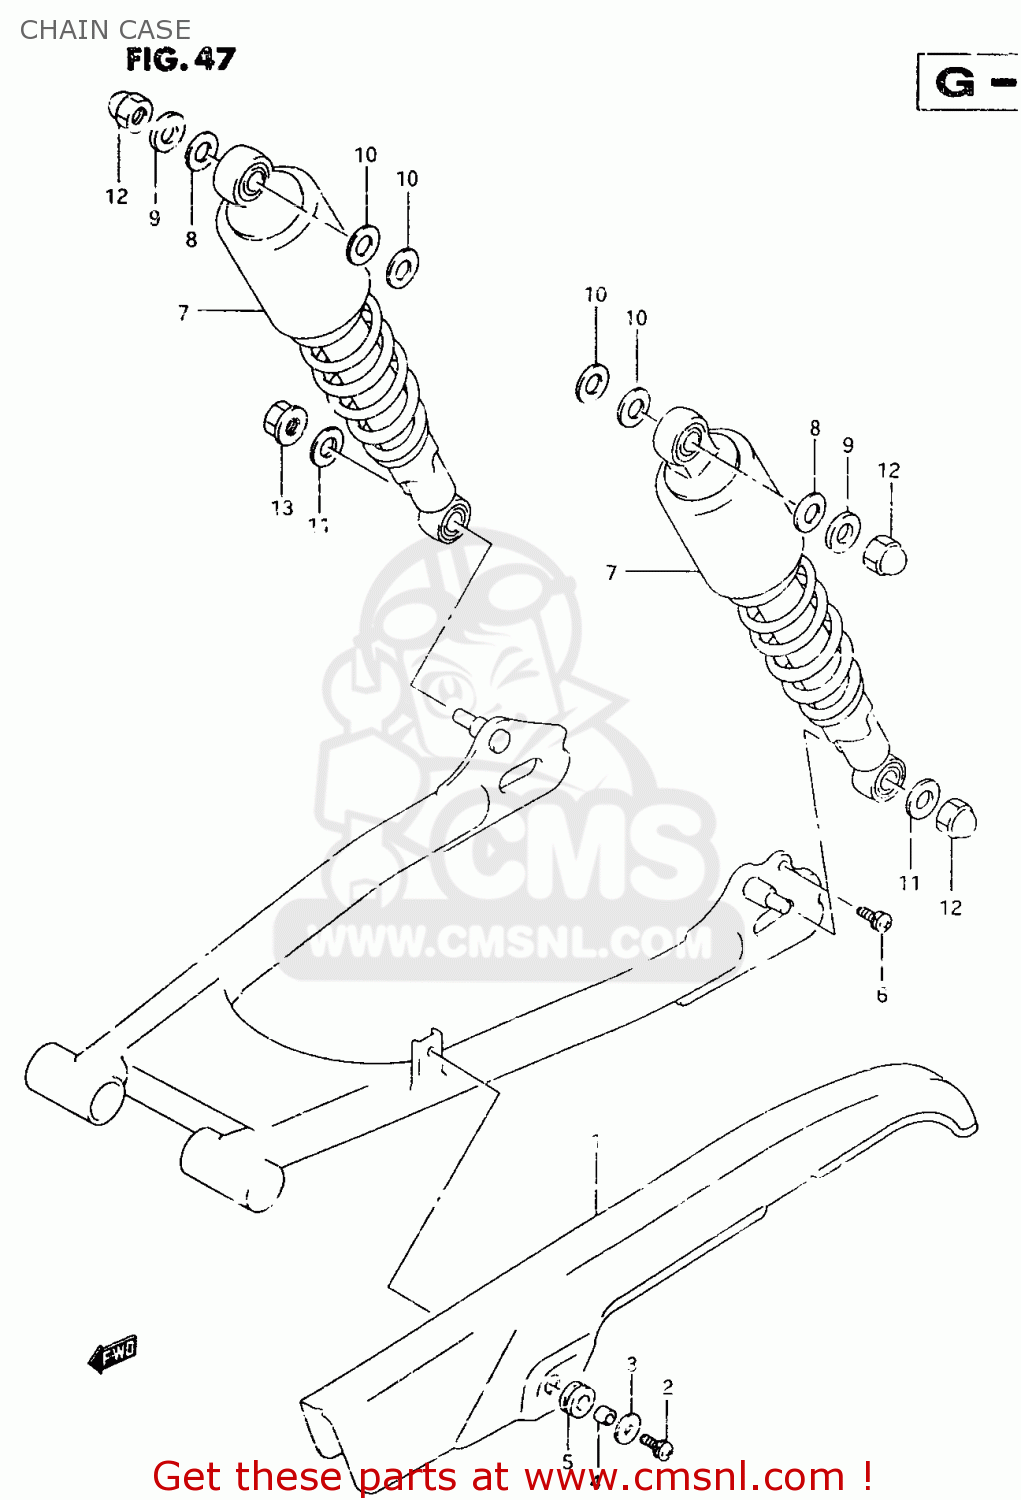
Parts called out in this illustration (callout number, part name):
1	CASE,CHAIN
2	SCREW
3	WASHER(6.5X20X1.2)
4	SPACER(6.5X9X7)
5	CUSHION
6	SCREW
7	ABSORBER ASSY,RR SHOCK
8	WASHER (10.5X24X2.3)
9	WASHER(10.5X24X3.2)
10	WASHER
11	WASHER (10.5X24X2.3)
12	NUT
13	NUT
